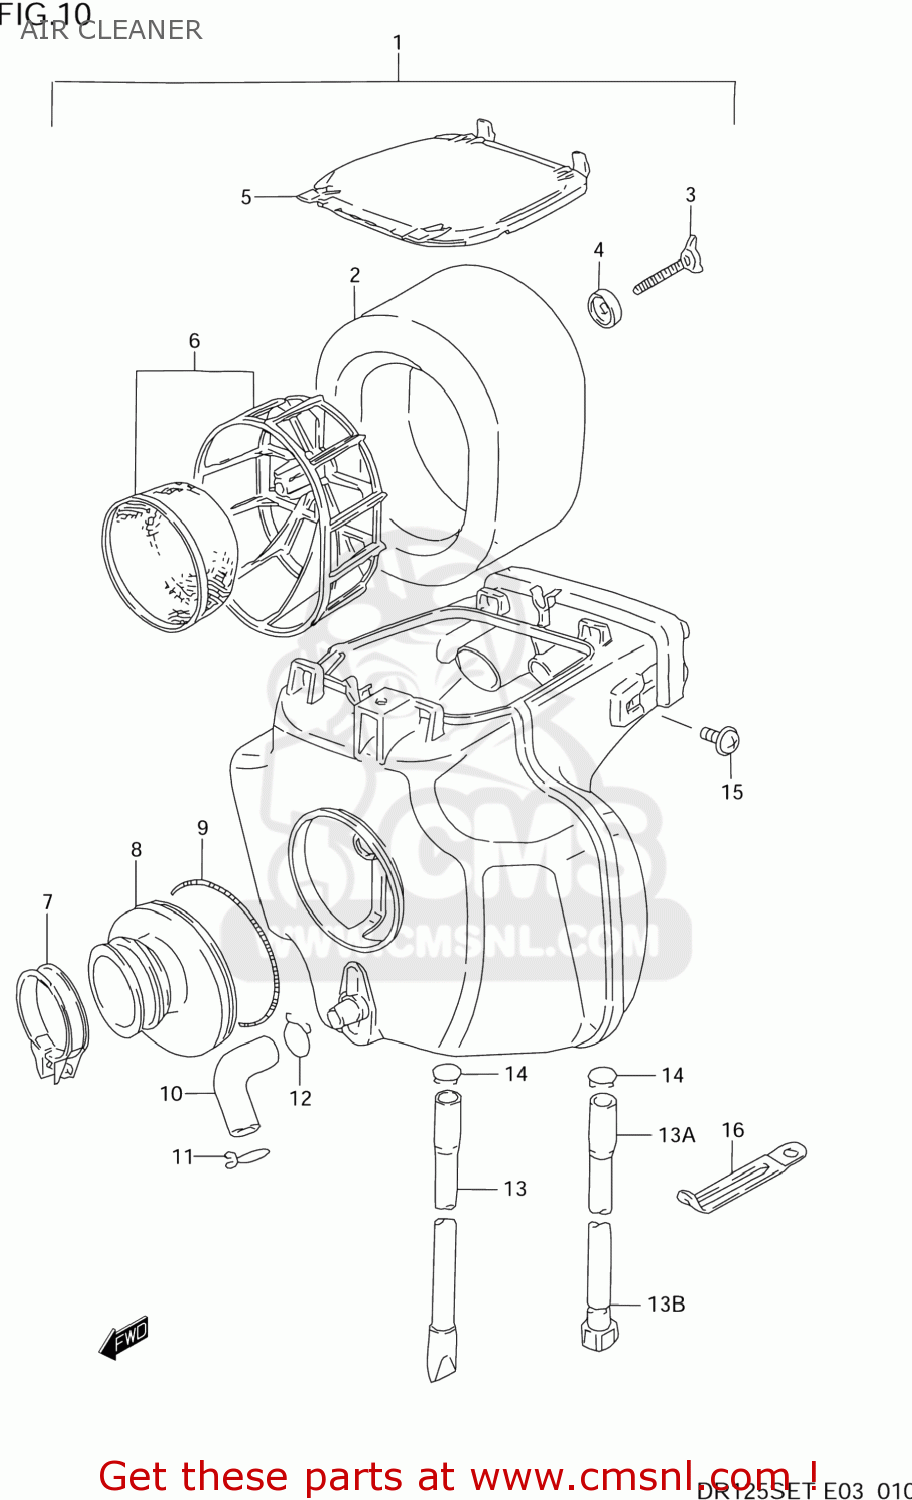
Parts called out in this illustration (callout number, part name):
1	CLEANER ASSEMBLY,AIR
2	FILTER
3	BOLT,WING
4	WASHER,FILTER HOLDER
5	CAP
6	HOLDER
7	CLAMP
8	TUBE,AIR CLEANER OUTLET
9	CLAMP,AIR CLEANER SIDE
10	TUBE,BREATHER
11	CLIP
12	CLIP
13	DRAIN TUBE
13A	TUBE,DRAIN
13B	CLIP
14	CLIP
15	SCREW
16	CLAMP
